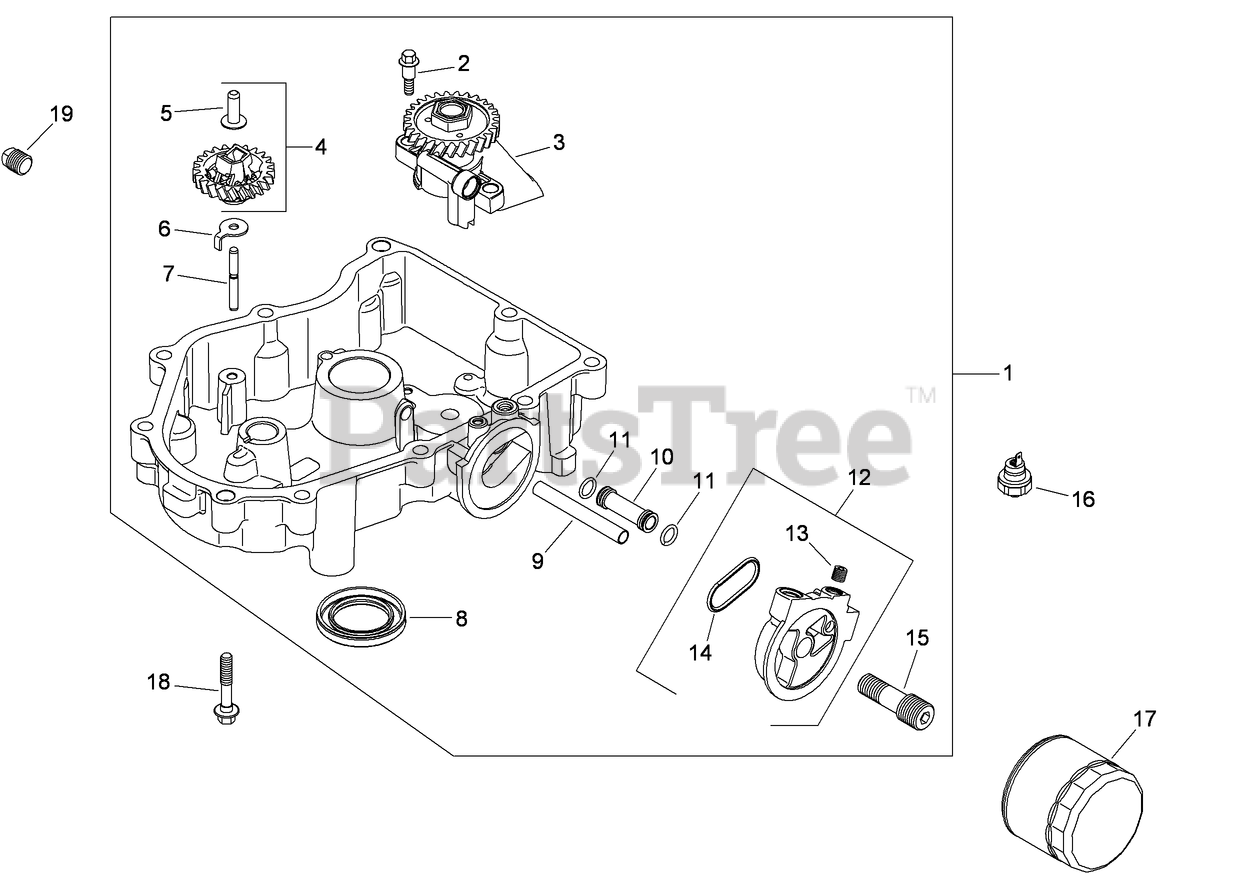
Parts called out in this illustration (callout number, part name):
1	OIL PAN ASM (INCLUDES 2-9, 11 [QTY 1], 24-27)
2	SCREW-SHOULDER, THD FRM (M6x1.0x26.5)
3	OIL PUMP ASM
4	GOVERNOR GEAR KIT W/PIN (INCLUDES 5)
5	PIN-REGULATING, GOVERNOR
6	TAB-LOCKING
7	SHAFT-GEAR, GOVERNOR
8	SEAL-OIL
9	TUBE-FEED, OIL (FILTER TO PAN)
10	TUBE-FEED, OIL (PAN TO FILTER)
11	O-RING
12	ADAPTER OIL FILTER KIT
13	PLUG-PIPE, COUNTERSUNK (1/8)
14	O-RING
15	NIPPLE-FILTER, OIL
16	SWITCH-PRESSURE, OIL
17	FILTER-OIL
18	SCREW-FLANGE (M8X1.25X45)
19	PLUG-PIPE, SQ HD (3/8)
